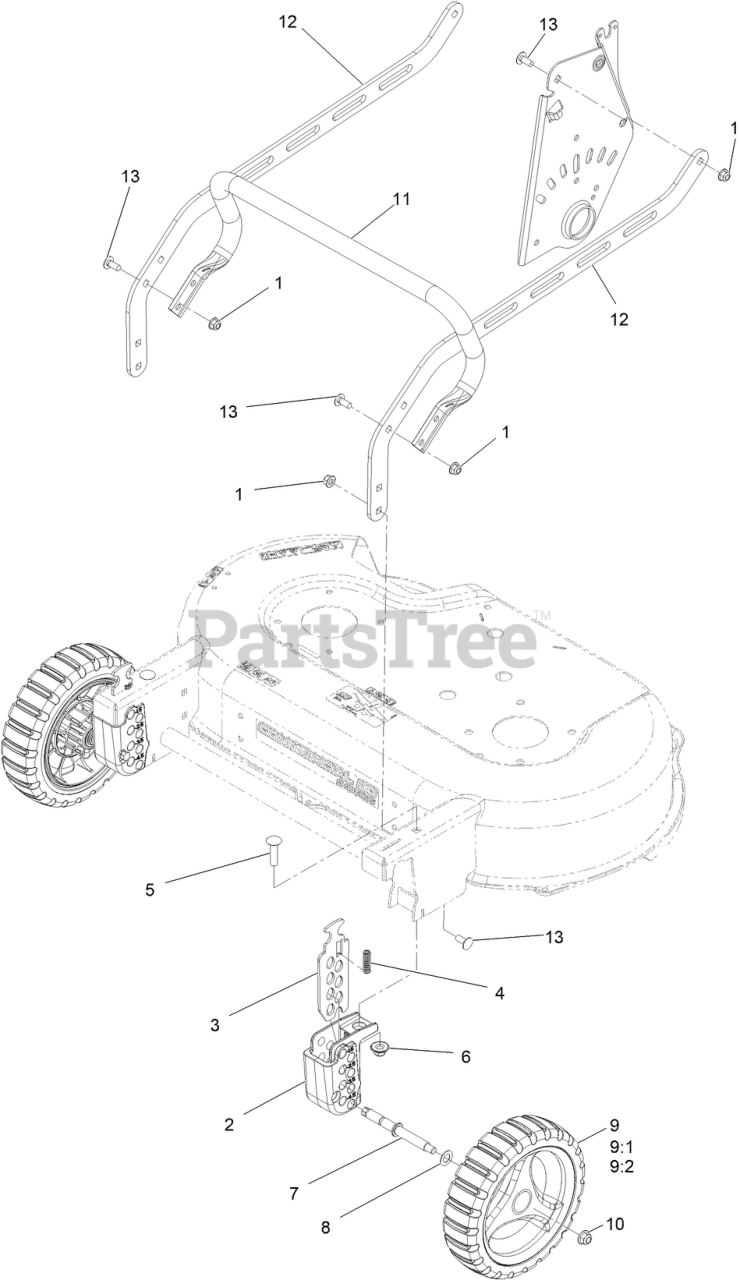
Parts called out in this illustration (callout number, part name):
1	NUT-HF, NI
2	BLOCK-FRONT QUADRANT
3	PLATE, FRONT HEIGHT
4	SPRING-COMPRESSION
5	SCREW-CARR
6	Nut-Nyloc 3/8-16 Flg
7	AXLE-WHEEL
8	WASHER-PLAIN
9	WHEEL ASM, 9" W/BEARINGS
9:1	WHEEL ASM, 9
9:2	BEARING-BALL
10	NUT-HF, NI
11	GUARD-ECV30 FRONT MOTOR
13	SCREW-CARR
